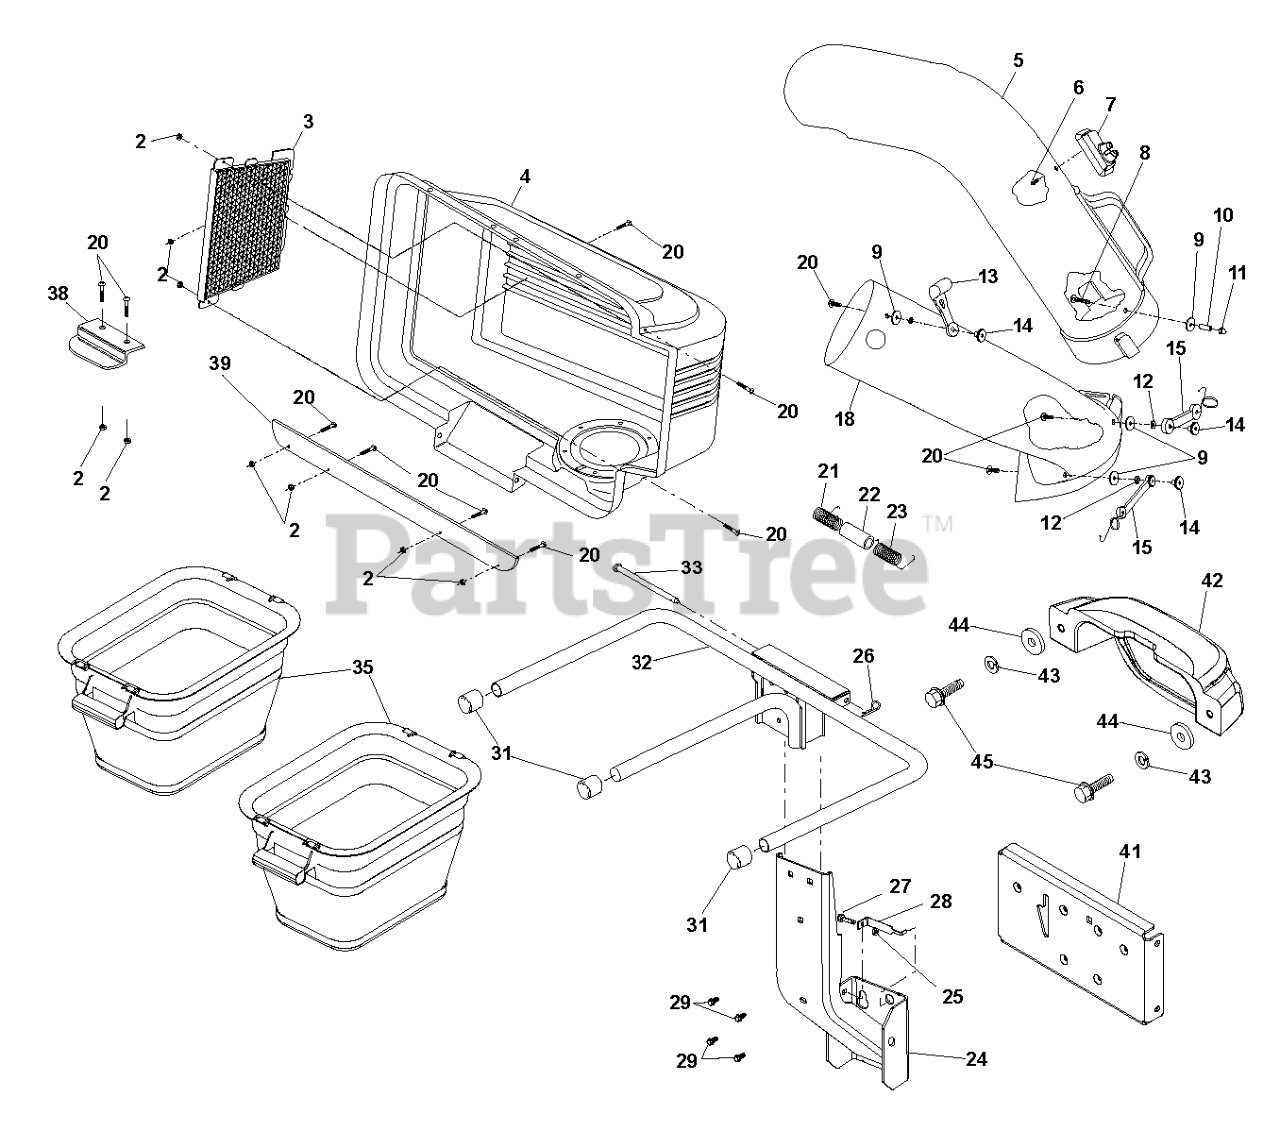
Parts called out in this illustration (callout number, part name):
3	COVER SCREEN
4	COVER.ASM.BAG.W/STRIP
5	CHUTE.UPPER.46"
7	INDICATOR ASM BAG
8	SCREW
9	RP STEEL WASHER
11	NUT
12	LOCKWASHER #10
13	LATCH.HOOD.
14	WELDNUT
15	LATCH ASSY
18	CHUTE.LOWER.LRV.26
20	SCREW
21	SPRING COVER LH
22	SPACER.COVER.BAGGER
23	SPRING COVER RH
24	POST.SUPPORT.BAGGER.BLACK
25	NUT.1/4-20.HEX.NYLOC.ZD
26	CLIP,INSULATOR
28	STOP BRACKET, BAGGER 2 BIN
29	SHOULDER BOLT 5/16-18TT
31	PLUG, TUBING END
32	FRAME.ASM.BAGGER.2BIN.QC42B
33	BAGGER.HINGE.PIN
38	LATCH CER38
39	STRIP.REINFORCE.BAGGER.2BIN.BL
41	COVER.BAGGER.REAR.LRV.BLACK
42	COUNTERWEIGHT G26LRV
43	WASHER M
44	WASHER.LOCK.HVY.HLCL.SPR.5/16
45	BOLT.FIN.HEX.5/16-18UNC X 1.00
